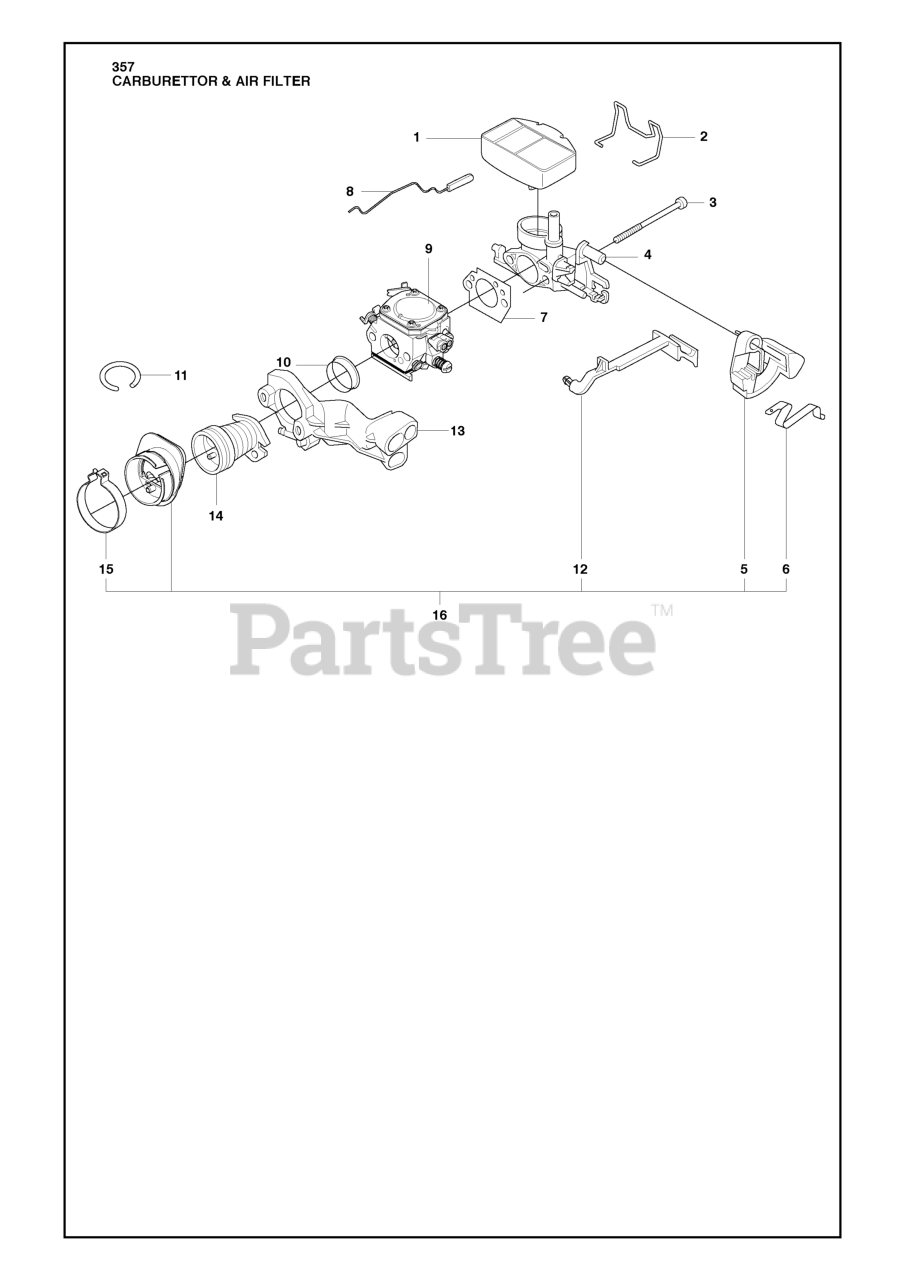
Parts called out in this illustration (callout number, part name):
1	AIR FILTER - NYLON (80)
1	AIR FILTER - NYLON (44)
1	AIR FILTER - FELT
3	SCREW MC6S 5X50
4	FILTER HOLDER
8	THROTTLE ROD
9	RP CARBURETOR
10	SUPPORT RING
11	HOSE, IMPULSE
12	CHOKE CONTROL
15	CLAMP, INTAKE
16	PARTITION WALL INTAKE
